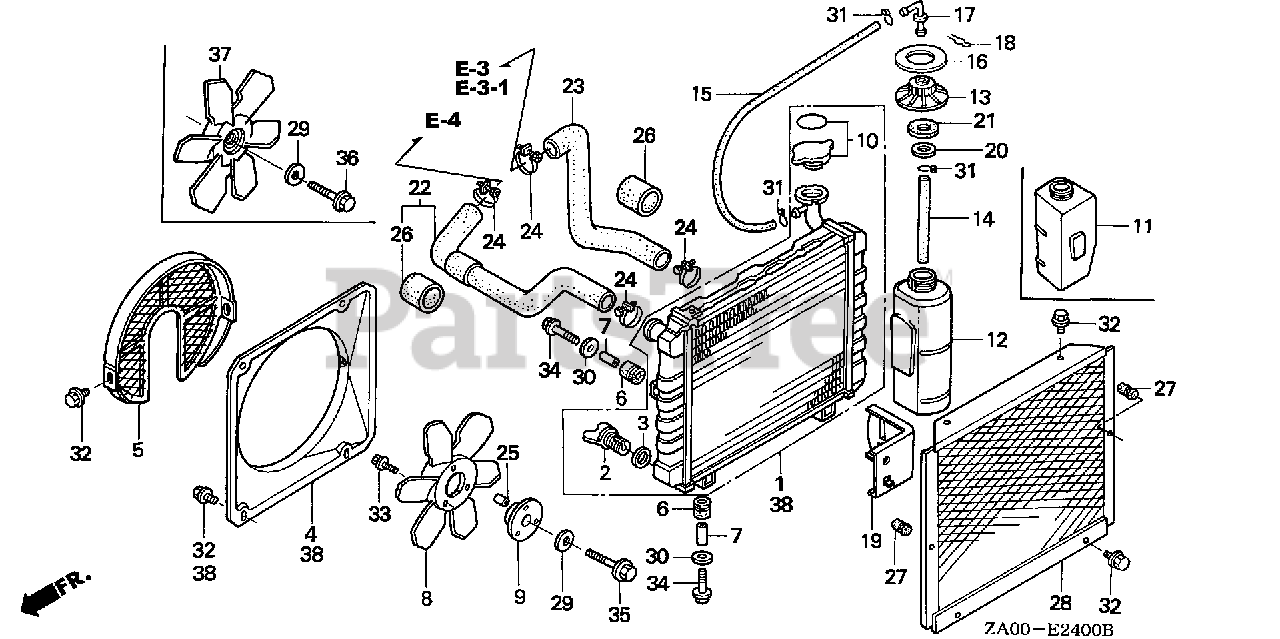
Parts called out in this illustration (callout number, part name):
1	RADIATOR
2	VALVE, DRAIN (TOYO)
3	GASKET, DRAIN (TOYO)
4	SHROUD
5	COVER, FAN
6	RUBBER, RADIATOR MOUNTING
7	COLLAR, DISTANCE
10	CAP, RADIATOR (DENSO)
11	TANK ASSY., RESERVE
13	CAP, RESERVE TANK
14	HOSE, RESERVE TANK
15	TUBE, RESERVE TANK
16	MARK, RESERVE TANK
17	JOINT, RESERVE TANK
18	CLIP, RESERVE TANK JOINT
22	HOSE, WATER (UPPER)
23	HOSE, WATER (LOWER)
24	CLIP, WATER HOSE
26	PROTECTOR, HOSE
27	RUBBER B, BATTERY HOLDER
28	COVER, RADIATOR
29	WASHER, LOCK
30	WASHER, WHEEL (6MM)
31	CLIP, TUBE (C11)
32	BOLT, FLANGE (6X8)
36	BOLT, FLANGE (8X28)
37	FAN, COOLING
